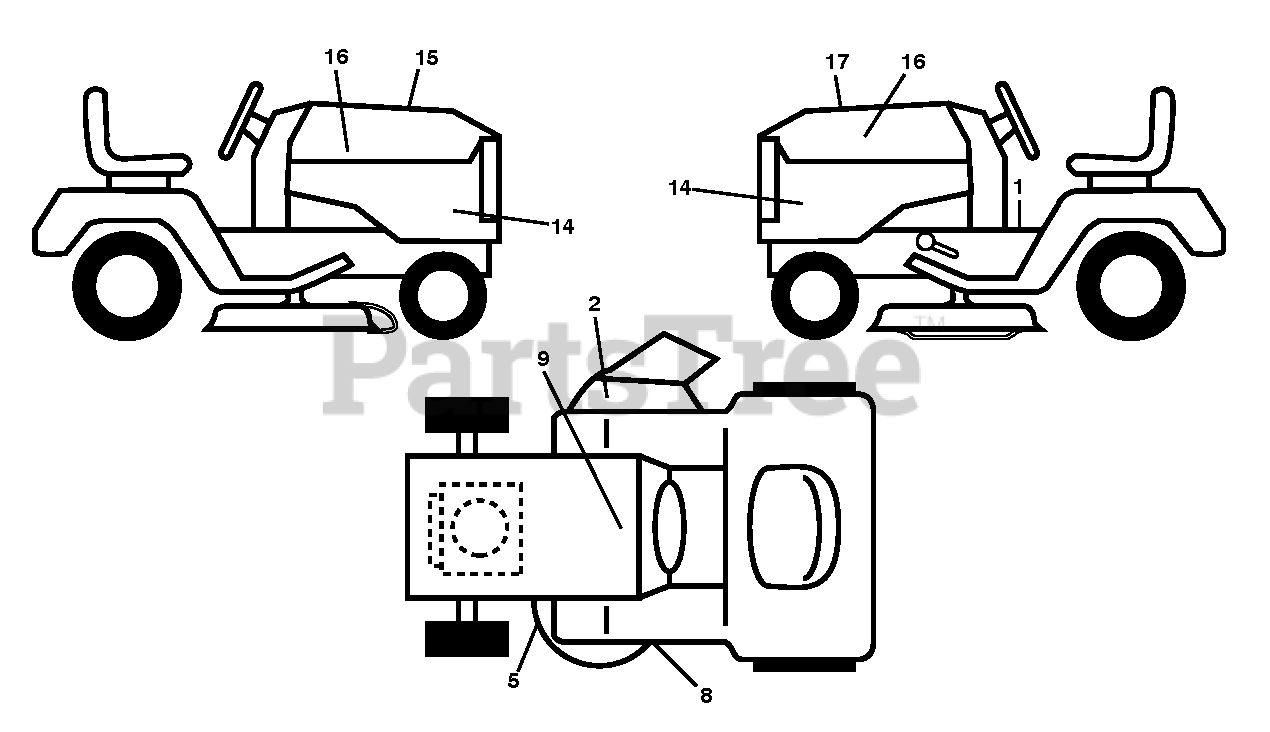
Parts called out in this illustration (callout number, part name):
1	DECAL.FENDER.WARNING
2	DECAL.WARN.KEEP.HAND.AWAY
5	DECAL.MOWER
8	DECAL.MOWER.SCH.48/54
9	DECAL BTRY SYMBOLS
14	DECAL.SIDE.PANEL.YTH24K48
15	DECAL.WARNING.CUST.RESP.E85.
16	RP.DECAL.BADGE.170MM.TEXTLOGO
